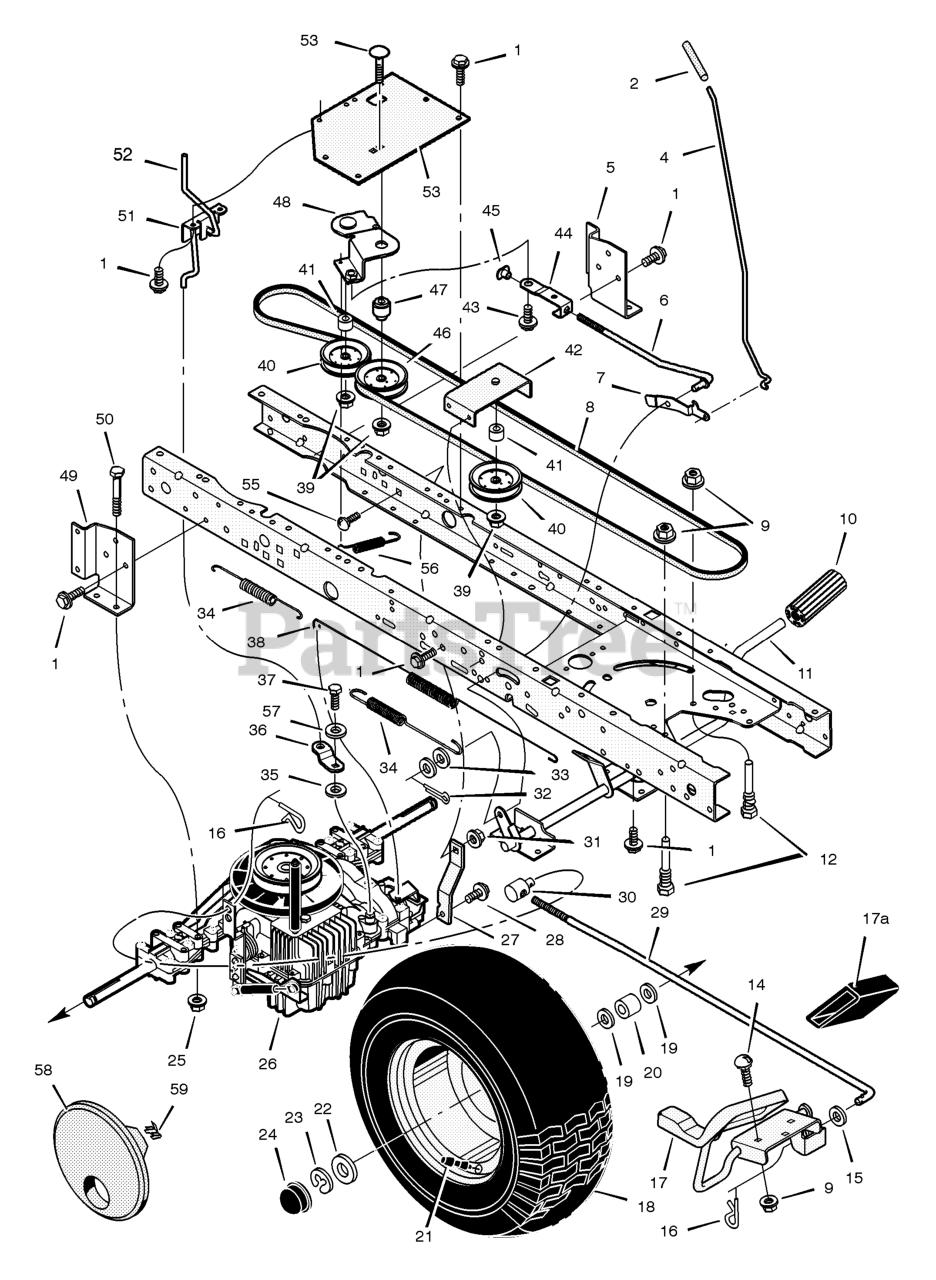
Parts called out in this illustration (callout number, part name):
2	Grip, Parking Brake
4	Rod, Parking Brake
5	Bracket, Transaxle - Left
6	Rod, Clutch
7	Latch, Parking Brake
8	V--Belt, Drive
9	Nut, Flange
10	Pedal, Brake/Clutch
11	Assembly, Brake Pedal
12	Screw, Guide
14	Bolt, Carriage
16	Pin, Hair
17	Pedal Assembly, Hydro
17A	Pad, Hydro Pedal
18	Wheel & Tire Ass'y - Rear 20"
20	Spacer
21	Stem, Valve
24	Cap, Hub
25	Nut, Centerlock
26	Transaxle **
27	Strap, Torque
29	Rod, Control
30	NUT, Adjusting, 1/2-13
31	Nut, Centerlock
32	Pin, Cotter
34	Spring, Extension
36	ARM, Disconnect
37	Capscrew
38	Spring, Brake
39	Locknut, Flange
40	Pulley, Idler
42	Bracket, Idler Assembly
43	Bolt, Shoulder
44	Link, Clutch
45	Nut, Tee
46	Pulley, Idler
47	Bushing, Pivot
48	Arm Assembly, Idler
49	Bracket, Transaxle --Right
50	Bolt, Hex
51	Bracket, Disconnect
52	Rod, Disconnect
53	Bracket, Idler Pivot
54	Bolt, Carriage
55	Bolt, Carriage
56	Spring, Clutch
58	Cover, Wheel
59	Retainer
